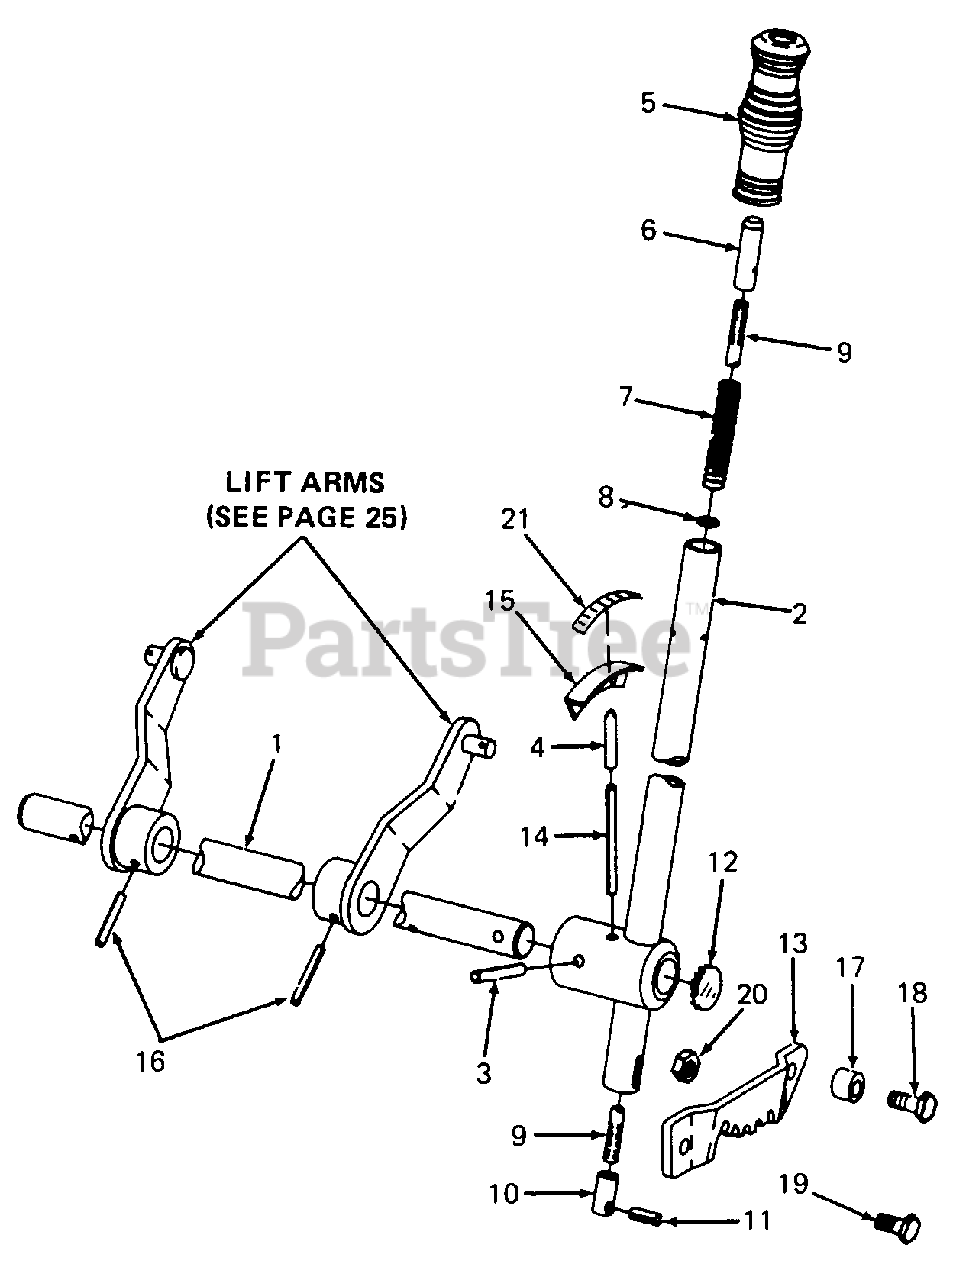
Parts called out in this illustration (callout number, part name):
1	Shaft, Lift
2	Lever, Lift
3	Pin, 3/8 X 1-3/4 Pln Slt-Spr
4	Pointer, Lift
5	Grip, Lift Handle
6	Pin, Release
7	Spring, Lift Handle
8	Washer, .344 X .532 X .06 Hdn Flat
9	Rod, Handle
10	Rod, Handle Release
11	Pin, 5/16 X 1-3/8 Hvy Pln Cld Spr
12	Plug, 1.0 Button
13	Ratchet, Handle
14	Pin, 3/16 X 3 Slotted Roll Spr
15	Bracket, Height Indicator
16	Pin, 1/4 X 1-1/2 Slotted Roll
17	Bushing, .395 X .62 X .43
18	Bolt, 3/8 X 1-1/2 GR 5
19	Bolt, 3/8 X 1 GR 5
20	Nut, 3/8 Center L GR 5
21	Label, 5 Position
